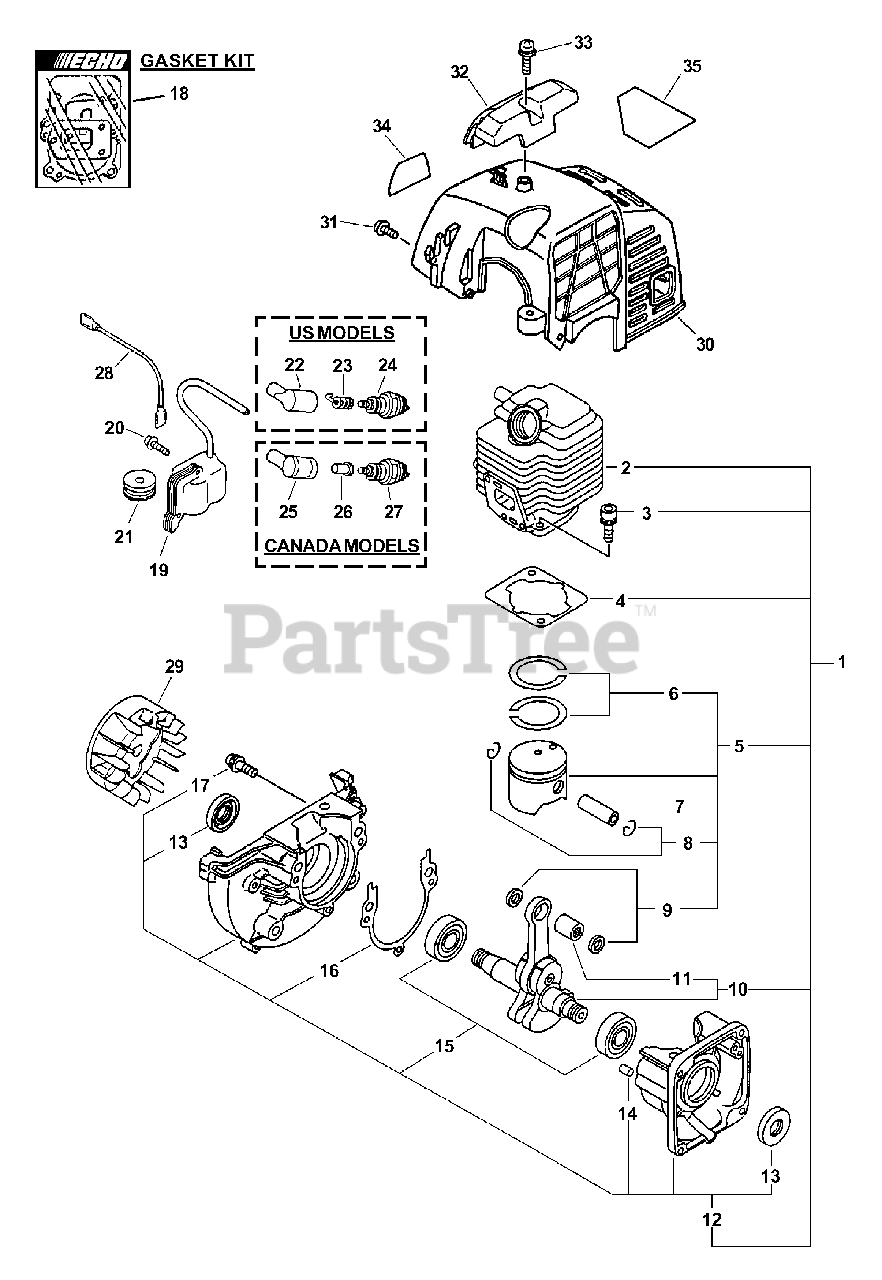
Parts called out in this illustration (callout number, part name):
1	SHORT BLOCK -- SB1027
2	CYLINDER
3	SCREW - 5X22
4	GASKET, CYLINDER
5	PISTON KIT
6	RING, PISTON
7	PIN, PISTON
8	RING, RETAINING
9	SPACER, PISTON
10	CRANKSHAFT ASSY
11	BEARING, NEEDLE - 8
12	CRANKCASE KIT
13	SEAL, OIL
14	PIN - LOCATING
15	BEARING, BALL - 6201
16	GASKET, CRANKCASE
17	SCREW - 5X28
18	GASKET KIT
19	COIL, IGNITION
20	SCREW - 4X22
21	GROMMET
22	CAP, SPARK PLUG
23	TERMINAL, SPARK PLUG CAP
24	SPARK PLUG -- BPM-7Y
25	CAP, SPARK PLUG
26	ADAPTER, SPARK PLUG CAP
27	SPARK PLUG -- BPMR-7A
28	LEAD - IGNITION
28	FLYWHEEL
29	GUARD, ENGINE
30	COVER, ENGINE - ORANGE
31	SCREW - 4X12
32	GUARD, TOP - BLACK
33	SCREW - 5X16 -- TAPPING
34	LABEL - MODEL PPT-2400 T1E
35	LABEL - CAUTION
